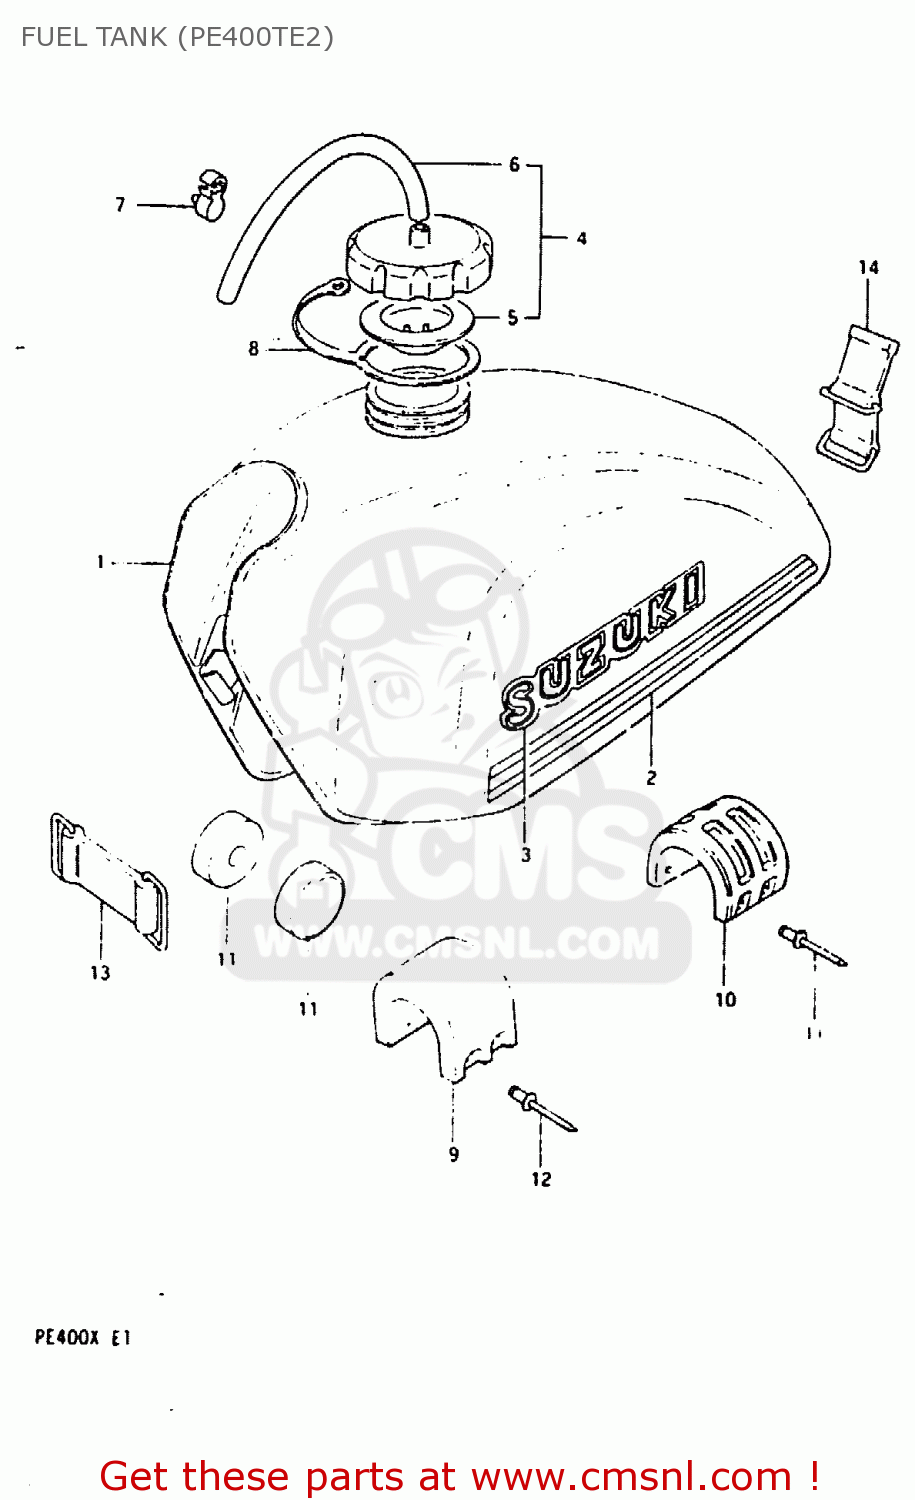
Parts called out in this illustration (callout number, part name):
1	TANK, FUEL (YELLOW)
2	TAPE SET
3	EMBLEM
4	CAP ASSEMBLY,FUEL TANK
5	GASKET,FUEL TANK CAP (NAS)
6	HOSE
7	CLAMP,BREATHER HOSE
8	BAND,FUEL TANK CAP
9	CUSHION, UPPER FRONT
10	CUSHION,FUEL TANK,CENTER
11	CUSHION
12	RIVET
13	BAND
14	BNAD, REAR
